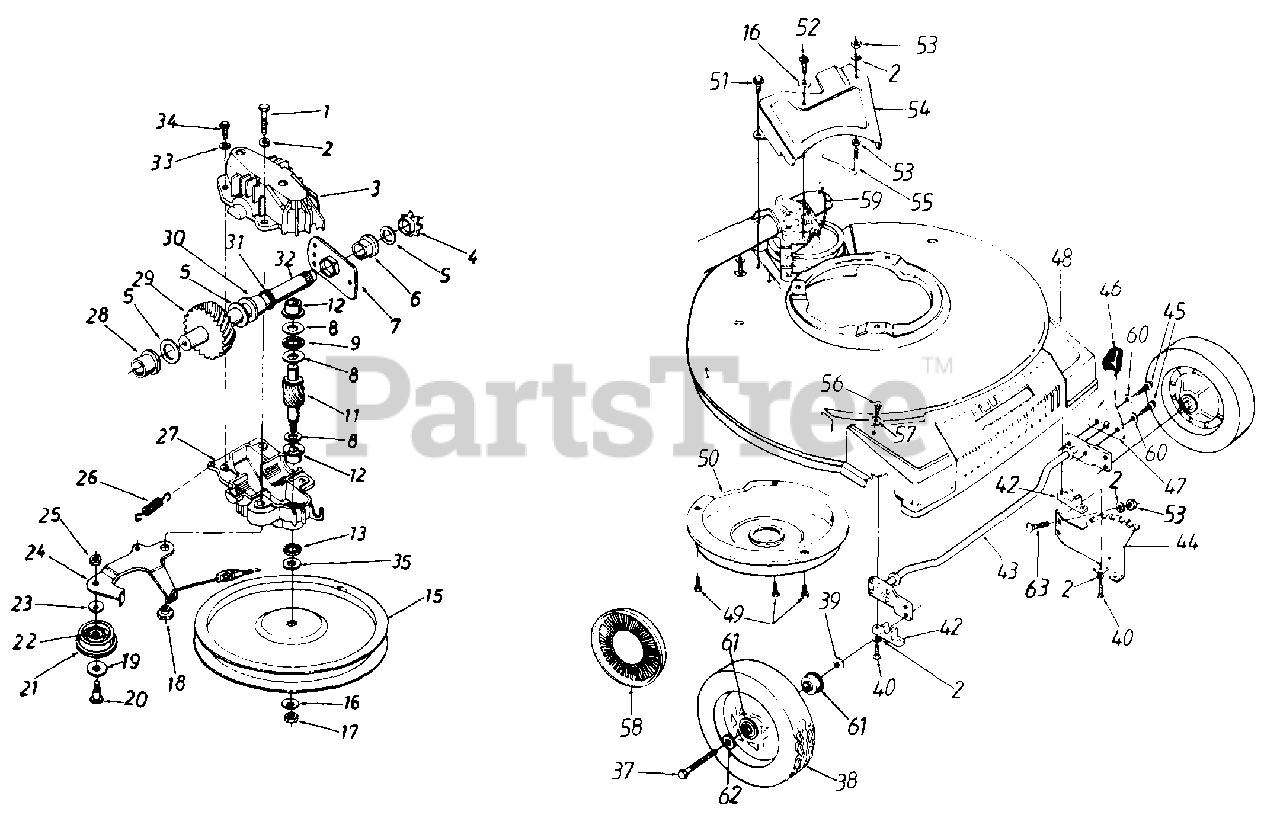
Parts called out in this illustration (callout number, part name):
1	Hex Patch Bolt 1/4-20 x 1.25"
2	L-Wash. 1/4" I.D.
3	Upper Hsg. Half
4	#48 Sprocket 7T x 1/2 Pitch
5	Fl-Wash. 5/8" I.D. x .030"
6	Hex Flange Brg..631" I.D.
8	Thrust Wash. .382" I.D. x .70" O.D.
9	Thrust Bearing .375" I.D. x .812" O.D.
11	11 Tooth Pinion Shaft
12	Flange Bearing
15	Fl-Pulley 5.06" O.D.
16	Bell-Wash. .265" I.D. x .75"
17	Hex L-Nut 1/4-28 L.H. Thd.
18	Shld. Spacer .375" Dia. x .170
19	Fl-Wash. .390" I.D. x 1.0"
20	Shld. Bolt .375" Dia. x .40"
21	Fl-Idler Plastic 1.50" Dia.
22	Needle Brg. .375" x .31
24	Idler Brk't. Ass'y.
25	Hex Patch L-Nut 1/4-28 Thd.
26	Extension Spring 1.12" Lg.
27	Lower Hsg. Half
28	Flange Bearing .566 Dia.
29	33 Tooth Helical Gear
30	Flange Bearing .629 Dia.
31	Oil Seal .625 Dia.
32	Gear Sprocket Shaft
33	L-Wash. #10 I.D.
34	Hex B-Tap Scr. #10 x .62"
35	Hex Washer .26" x .88"
37	Front Axle Bolt
38	Wheel Ass'y. Comp. 8 x 2"
39	Bell-Wash. .380" I.D. x .88
40	Hex B-Tap Scr. 1/4-20
42	Block Bushing
45	Hex TT-Tap Scr. 1/4-20 x .38"
46	Knob
47	Spring Lever
48	Plastic Front End
49	Hex B-Tap Scr. 1/4" x .38"
52	Hex Wash. Hd. B-Tap Scr. 1/4 x .62" (Spec.)
53	Hex Nut 1/4-20 Thd.
56	Truss B-Tap Scr. 5/16 x .75"
57	Bell-Wash. .345" I.D. x .88"
58	Hub Cap
59	S.P. Cable 44" Lg.
60	External L-Wash. 1/4" I.D.
61	Ball Bearing 1/2" I.D.
62	Wave Wash. .53" I.D. x .78"
63	Carr. Bolt 1/4-20 x .5" Lg.
